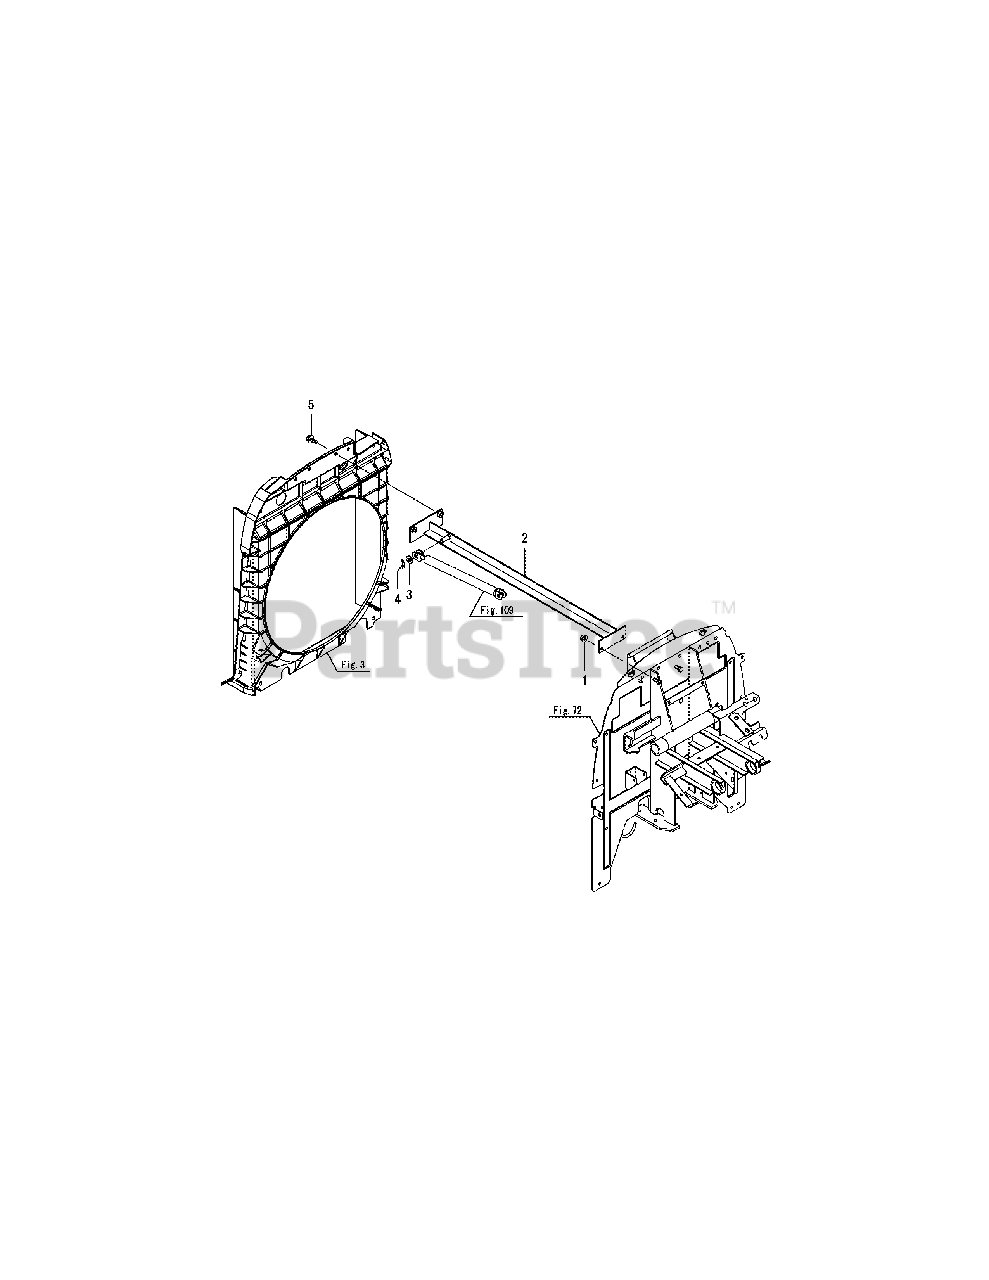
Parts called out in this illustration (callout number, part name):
1	NUT W/WASHER 8
2	FRAME ASSY, CONNECT
3	WASHER 10, POLISHED
5	BOLT M 8X 16 PLATED
